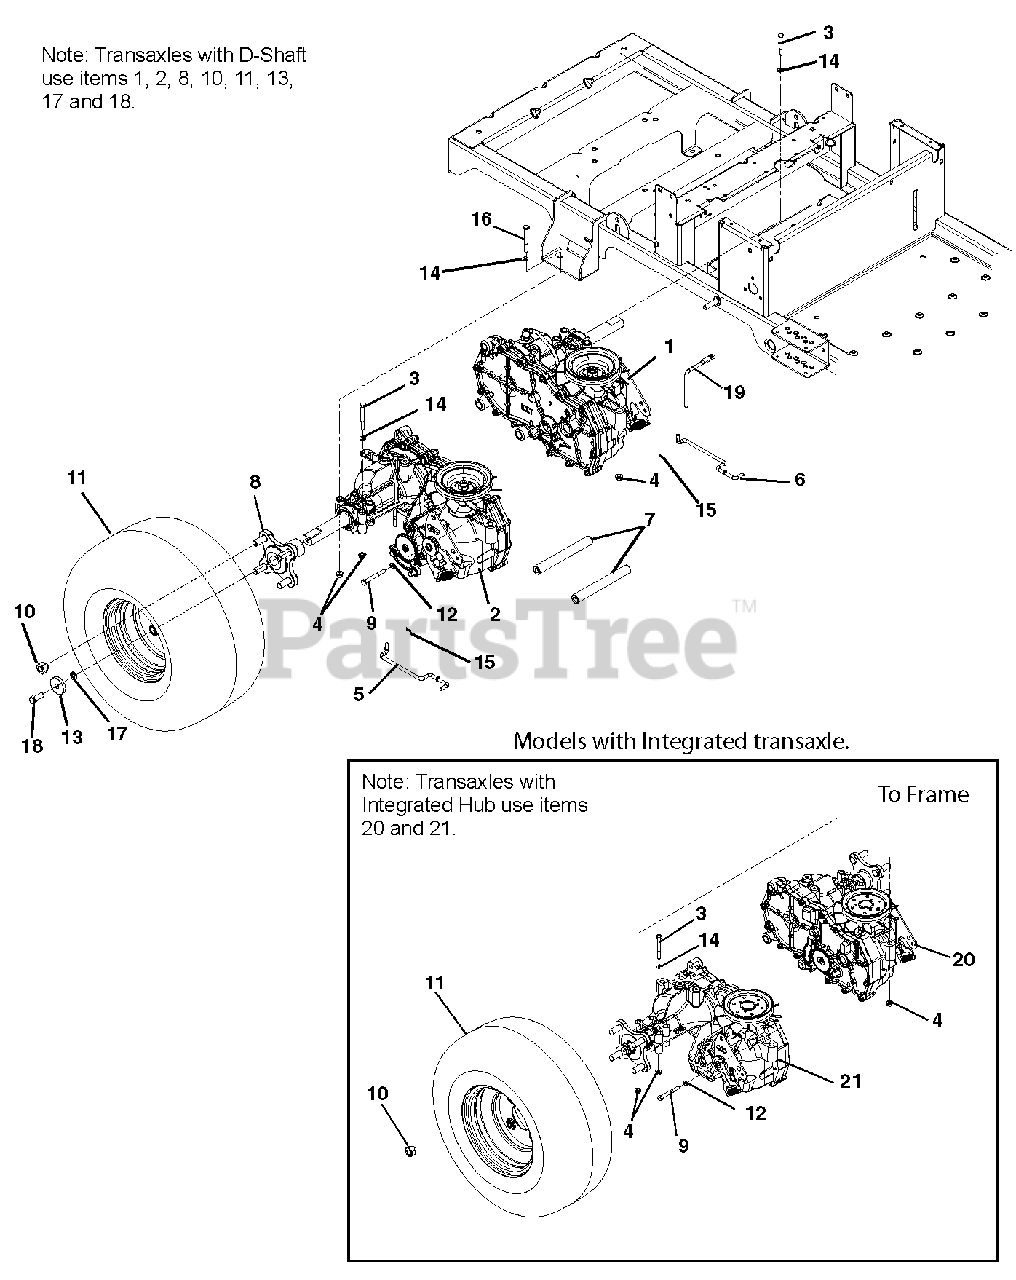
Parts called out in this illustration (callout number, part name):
1	Transaxle, Left Hand EZT D-Shaft
2	Transaxle, Right Hand EZT D-Shaft
3	Bolt, Hex .31-18 x 2.25 Grade 5
4	Nut 5/16-18 Flange Nyloc
5	Dump Valve, Right Hand
6	Dump Valve, Left Hand
7	Shaft, Cross Brace
8	Assembly, Wheel Hub
9	Bolt-Hex .38-16 x 2.50 Grade 5
10	Nut, Wheel .50-20 13/16
11	Tire/Wheel Assembly, 18 x 8.5-8 Center (142)
12	Washer, Flat Steel .406 x 1.00 x .188
13	Washer, Flat Steel .406 x 1.50 x .245
14	Washer, Flat-Steel .38 x .875 x .083
15	Pin-Hair-Internal .06 x .18 x .77
16	Bolt, Hex .31-18 x 2.75
17	Washer, Locking .38 x .094 Regular
18	Bolt, Hex .38-16 x 1.00 Grade 5
19	Belt Finger (141)
20	Transaxle, EZT Short Left Hand
21	Transaxle, EZT Short Right Hand
